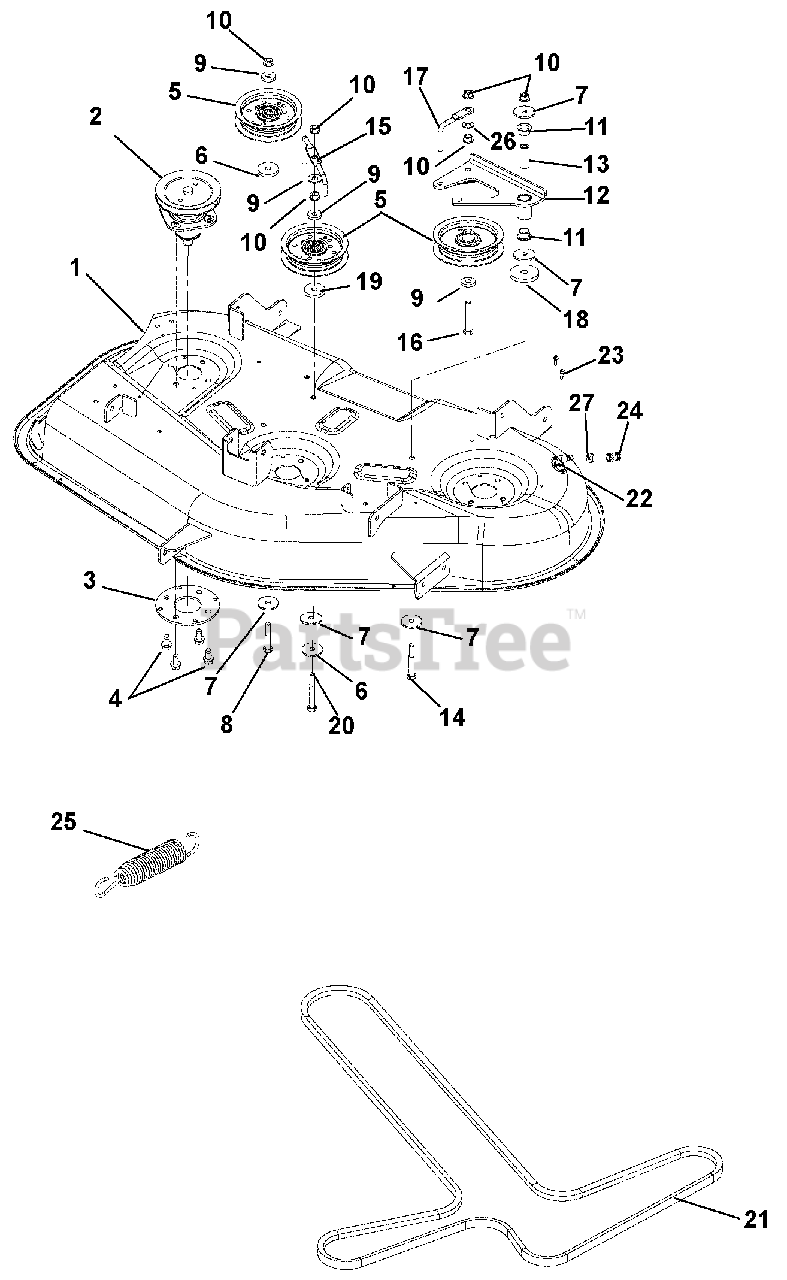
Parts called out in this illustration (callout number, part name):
1	Kit, 42" Gravely CE Deck and Decals
2	Assembly, Spindle
3	Plate, Spindle
4	Screw, Tapping .38-16 x .75 Hex Washer Head
5	Assembly, Idler 4"
6	Washer, Flat Steel .406 x 1.50 x .245
7	Washer, Flat Steel .380 x 1.50 x .125
8	Bolt, Hex .38-16 x 2.25
9	Washer, Flat Steel .406 x 1.00 x .188
10	Nut, Locking Top Flange .38-16
11	Bushing, Flange, .625 x .750 x .500 x 1.00
12	Idler Arm
13	Spacer, .375ID x .625 OD x 1.66
14	Bolt, Hex .38-16 x 3.00
15	Belt Finger
16	Bolt, Hex .38-16 x 2.25
17	Wireform Belt Finger
18	Washer, Flat Steel .469 x 2.00 x .25
19	Washer, Flat Steel .438 x 1.00 x .083
20	Bolt, Hex .38-16 x 2.75
21	V-Belt, 4L Wrapped
22	Assy, Washout Port W/O Ring
23	Screw, Tapping .25-20 x .62 Hex Washer Head Thread Rolling
24	Coupling, Quick Disconnect
25	Extension Spring .135 x .98 x 6.0
26	Washer, Flat Steel .406 x .812 x .065
27	O-Ring .362 X .103 X .568
